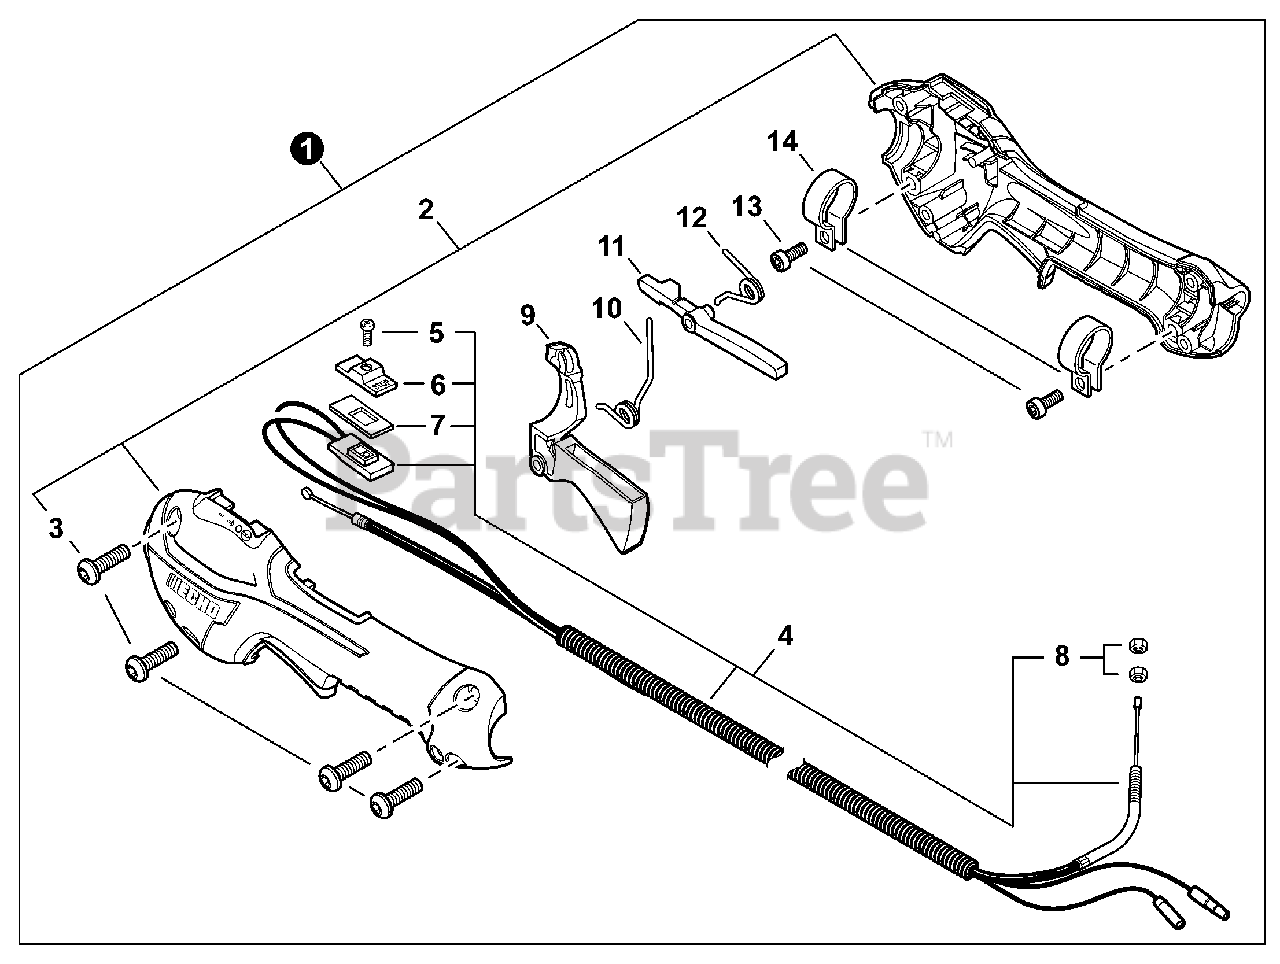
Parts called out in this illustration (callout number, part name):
1	CONTROL HANDLE ASSY
2	CONTROL HANDLE KIT
3	BOLT, TORX 5×16
4	CABLE ASSY, CONTROL
5	SCREW 3×10
6	KNOB, SWITCH - ORANGE
7	SEAL, SWITCH
9	TRIGGER, THROTTLE
10	SPRING, TORSION
11	LEVER, THROTTLE LOCKOUT
12	SPRING, TORSION
13	BOLT, TORX 5×16
